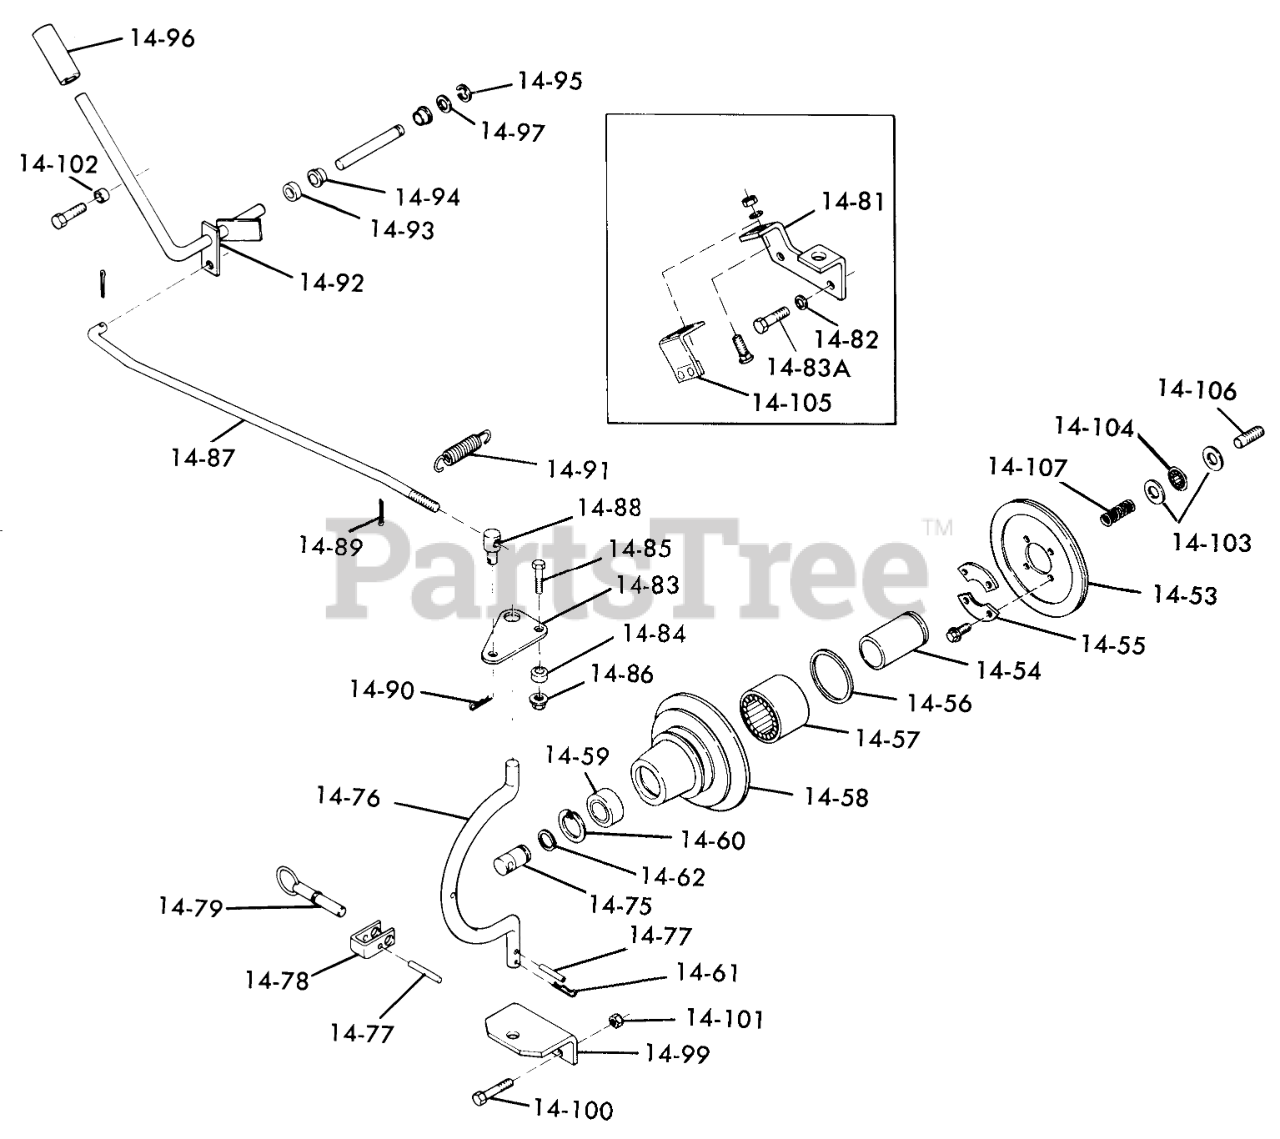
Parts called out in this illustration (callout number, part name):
14-54	RACE-BEARING
14-55	RETAINER
14-56	SEAL-OIL
14-61	Hairpin
14-75	SHAFT-PTO
14-77	PIN-SPIROL
14-82	LOCKWASHER
14-84	SPACER
14-88	TRUNNION
14-90	Hairpin Cotter
14-94	BUSHING-FLANGED
14-96	GRIP
14-103	RACE THRUST
14-104	THRUST BEARING
14-107	SPRING
